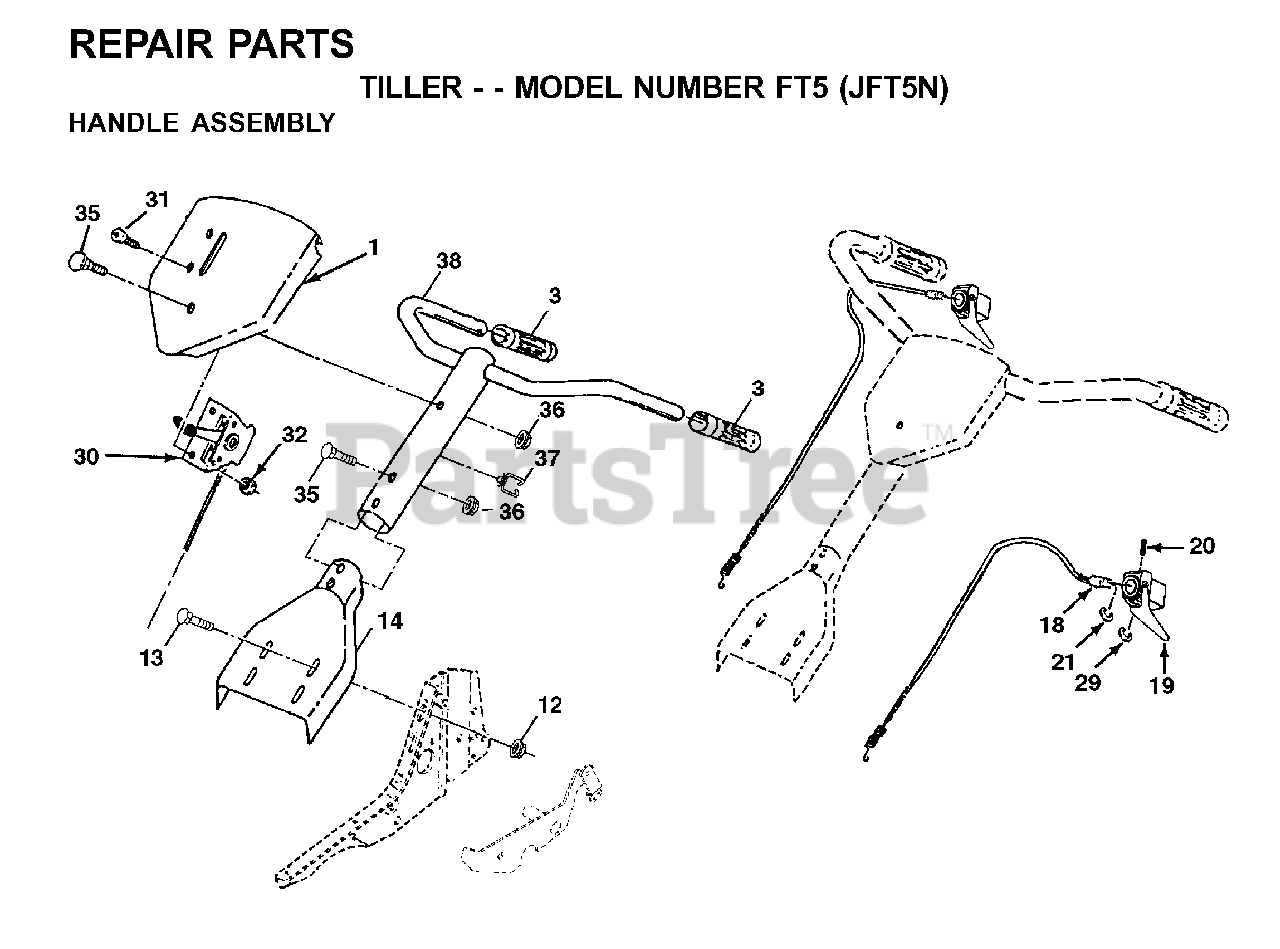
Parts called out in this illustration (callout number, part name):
12	NUT
13	BOLT.RH.SQNK.5/16
21	RETAINING RING
29	RETAINING RING
30	THROTTLE CONTROL
31	SCREW.PNHD.10-24
32	NUT **
35	BOLT.5/16-18X2.5
36	LOCKNUT-FLANGE 5/16-18
